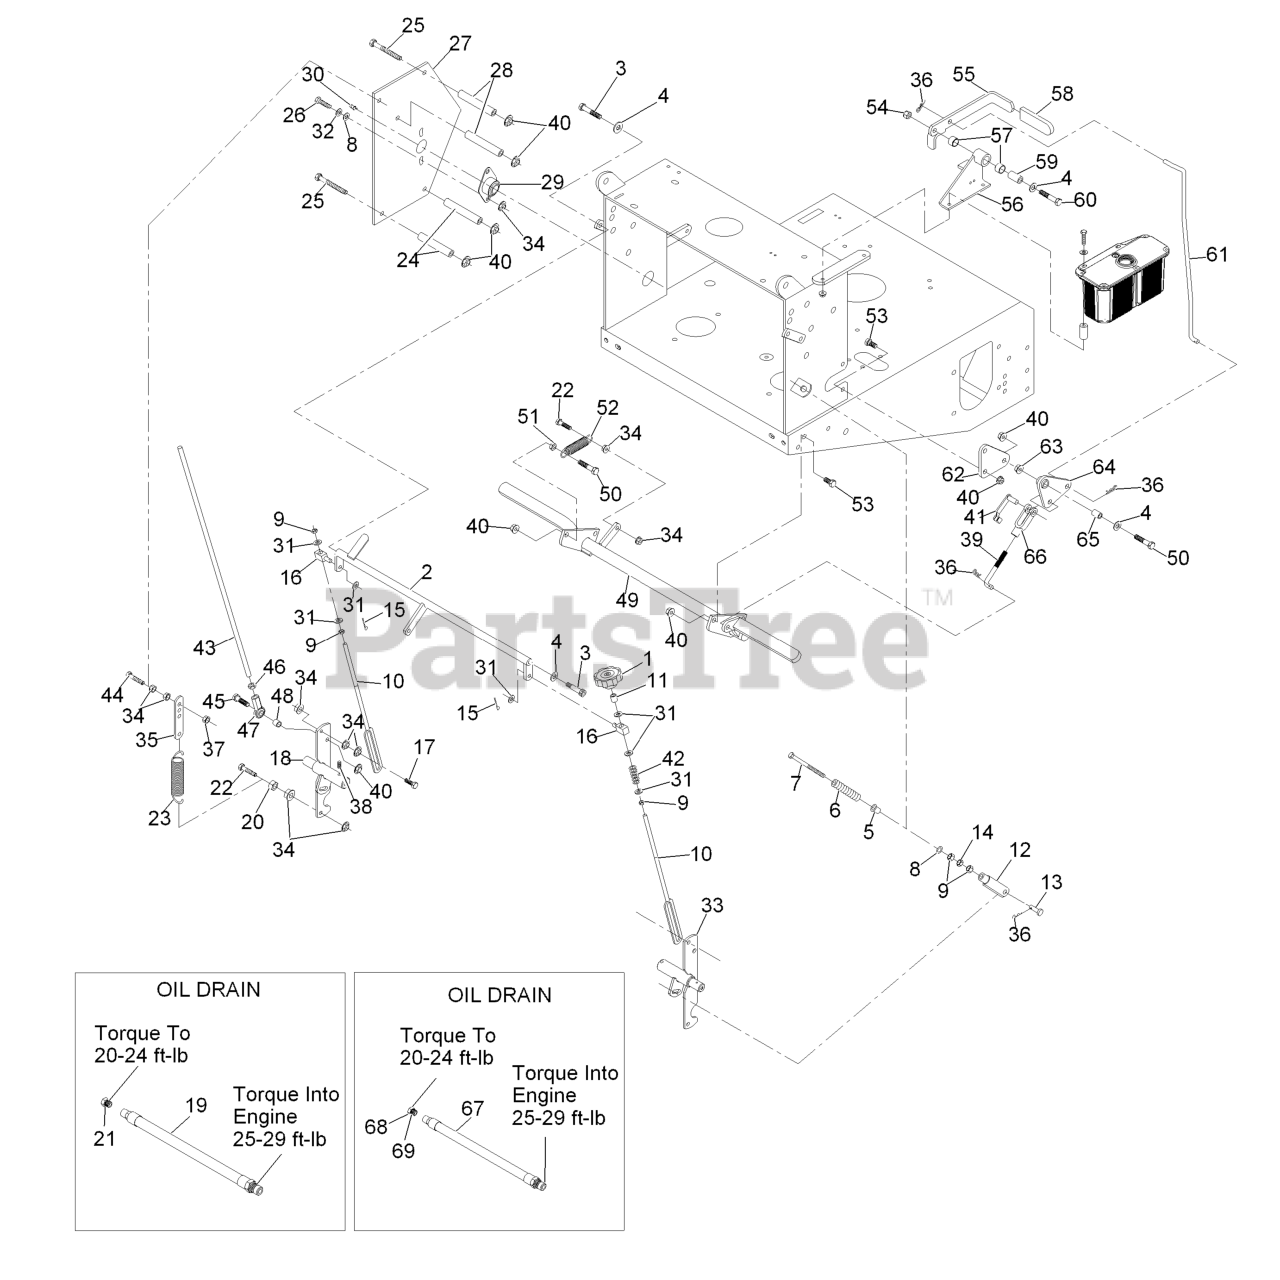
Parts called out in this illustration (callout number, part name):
1	KNOB-TRACKING
2	CRANK-CONTROL, SPEED
3	SCREW-HSH
4	WASHER-FLAT
5	BUSHING-FLANGED
6	SPRING,COMPRESSION (NEUT)
7	BOLT-RETURN, NEUTRAL
8	WASHER-FLAT
9	NUT-HEX
10	LINK-CONTROL, SPEED
12	YOKE-ADJUSTABLE
13	PIN-CLEVIS
14	NUT-JAM
15	PIN-COTTER
17	SCREW-HH
18	SHAFT-CONTROL, LH
20	NUT-JAM
22	SCREW-HH, SPECIAL
23	SPRING-EXTENSION
24	SPACER-SHIELD
25	SCREW-HH
26	SCREW-HH
27	SHIELD-CONTROL
28	SPACER-SHIELD
29	BEARING-FLANGE, SIDE
30	FITTING-GREASE
31	WASHER-PLAIN
32	WASHER-LOCK
33	SHAFT-CONTROL, RH
35	TAB-SPRING, EXTENSION
36	PIN-COTTER
37	NUT-LOCK, NI
38	SCREW-SET
39	LINKAGE-LOWER
40	NUT-HHF, WHIZ
41	PIN-SPRING, CLEVIS
42	SPRING-COMPRESSION
43	LINKAGE,DRIVE (PLT)
44	BOLT-TAP, HH
45	SCREW-HH
46	NUT-HEX JAM, LH
47	JOINT-BALL END, LH
48	SPACER-TUBE, PUMP LINK
50	SCREW-HH
51	NUT-JAM
52	SPRING-IDLER
53	SCREW-HH
54	NUT-LOCK, NI
55	LEVER,PARK BRK W/DECAL
56	BRACKET ASM
57	SLEEVE-BUSHING
58	GRIP-LEVER
59	BUSHING-PIVOT
60	SCREW-HH
61	LINKAGE-UPPER
62	BELLCRANK
64	BELLCRANK ASM
65	BUSHING-PLASTIC
66	YOKE-LINKAGE, BRAKE
67	ASM, ENGINE OIL DRAIN HOS
68	PLUG-HH
69	O-RING
